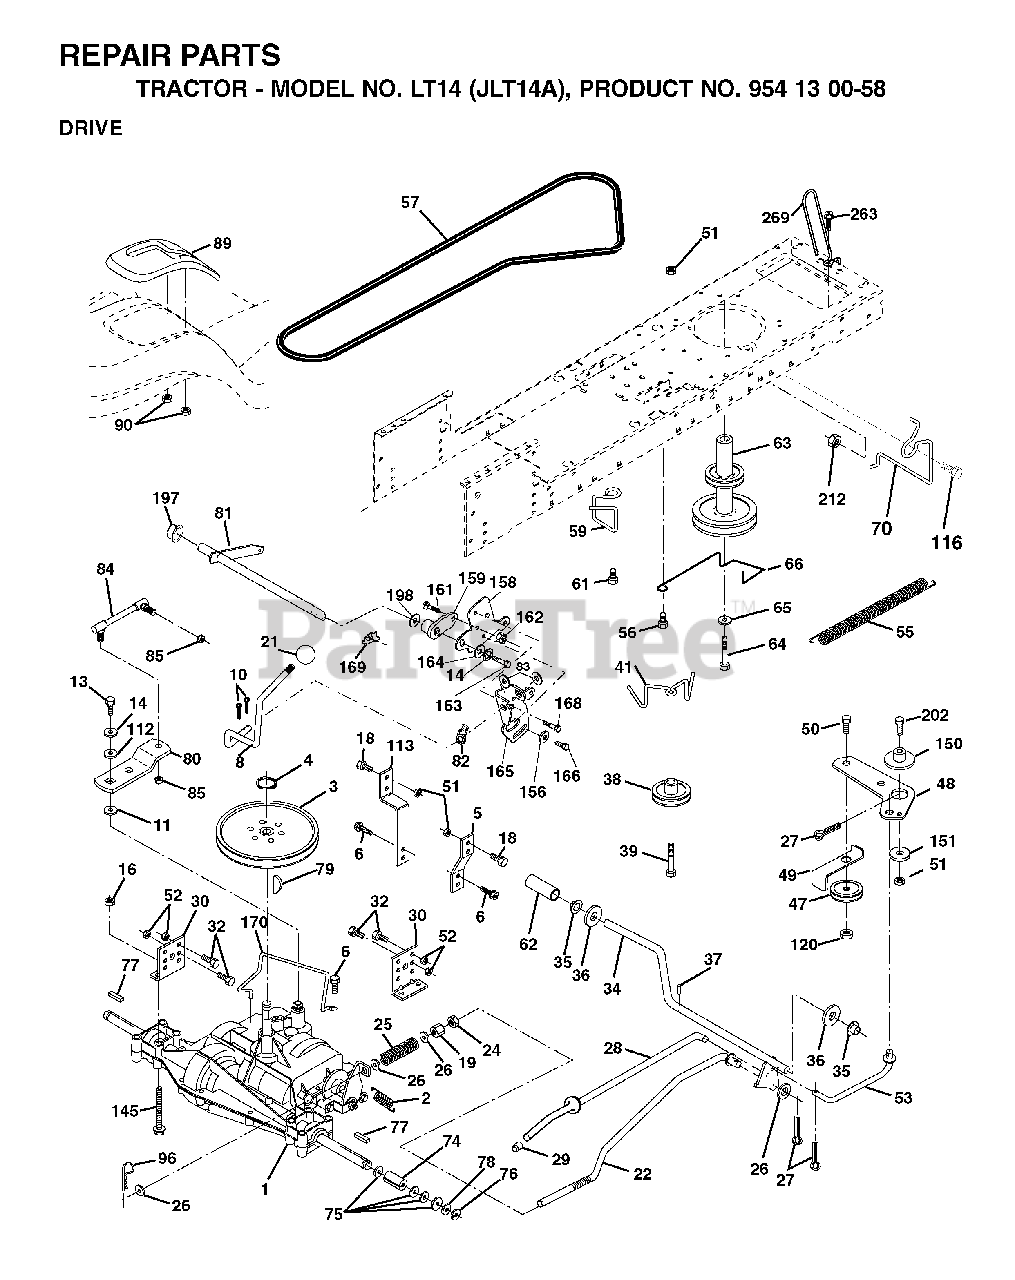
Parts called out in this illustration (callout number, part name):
2	SPRING,BRAKE RETURN
3	PULLEY TRANS
4	RETAINING RING LT
5	STRAP TORQUE
6	SCREW 5/16"
8	ROD SHIFT FENDER ADJUST STLT
10	PIN COTTER
11	WASH-SHFT PLT LT
13	BOLT 1/4-28X3/4
14	LOCKWASHER
16	NUT.71038.31-18.HEX.NYLOCK
19	NUT
21	KNOB.DUCKHEAD.1/2
22	ROD BRAKE
24	NUT
25	SPRING ROD LT
27	COTTER PIN
28	ROD, PARKING BRAKE
29	PLUNGER CAP
30	BRKT, MOUNT TRNSAXLE
32	BOLT
34	SHAFT, FOOT PEDAL
35	BEARING.NYLON
36	WASHER LT
37	DRIVE PIN
38	PULLEY IDLER COMPOSITE
39	BOLT
41	KEEPER, BELT IDLER
47	IDLER PULLEY
48	BELLCRANK, CLUTCH
49	RETAIN BELT
50	BOLT.3/8-16X1.50
51	LOCKNUT
52	LOCKNUT
53	LINK, CLUTCH LT
55	SPRING, RETURN LT
56	SCREW 3/8-16X3/4
57	V-BELT
59	KEEPER, BELT CENTER
61	SCREW 3/8-16X.875
62	PEDAL COVER T
64	BOLT
65	LOCKWASHER
66	KEEPER BELT ENGINE
74	SPACER AXLE
76	E-RING LT
77	SQUARE KEY
80	ARM SHIFT
82	SHIFT SPRING
83	WASHER
85	NUT LOCK CENTER 1/4 -28 FNTHD
89	CONSOLE.SHIFT.STLT.6SP.BLACK
96	RETAINER M
112	WASHER LT
113	STRAP TORQUE LH LT
116	BOLT D
120	NUT LOCK FLG 3/8-16 UNC
150	SPACER, RETAINER
151	WASHER 12/32X2X10GA
156	WASHER.SRRTD.5/16
158	BRACKET
159	HUB
161	BOLT
162	NUT.CROWNLOCK.1/4
165	RP BRACKET
168	BOLT.SHOULDER.5/16-18X
169	PLATE.FASTENING.CROSS.SHAFT
170	KEEPER BELT T/A
197	NYLINER SNAP 5/8" ID
198	WASHER.NYL.7/8IDX.105"HYD CR
202	BOLT
212	NUT
263	SCREW, 3/8-16X3/4
